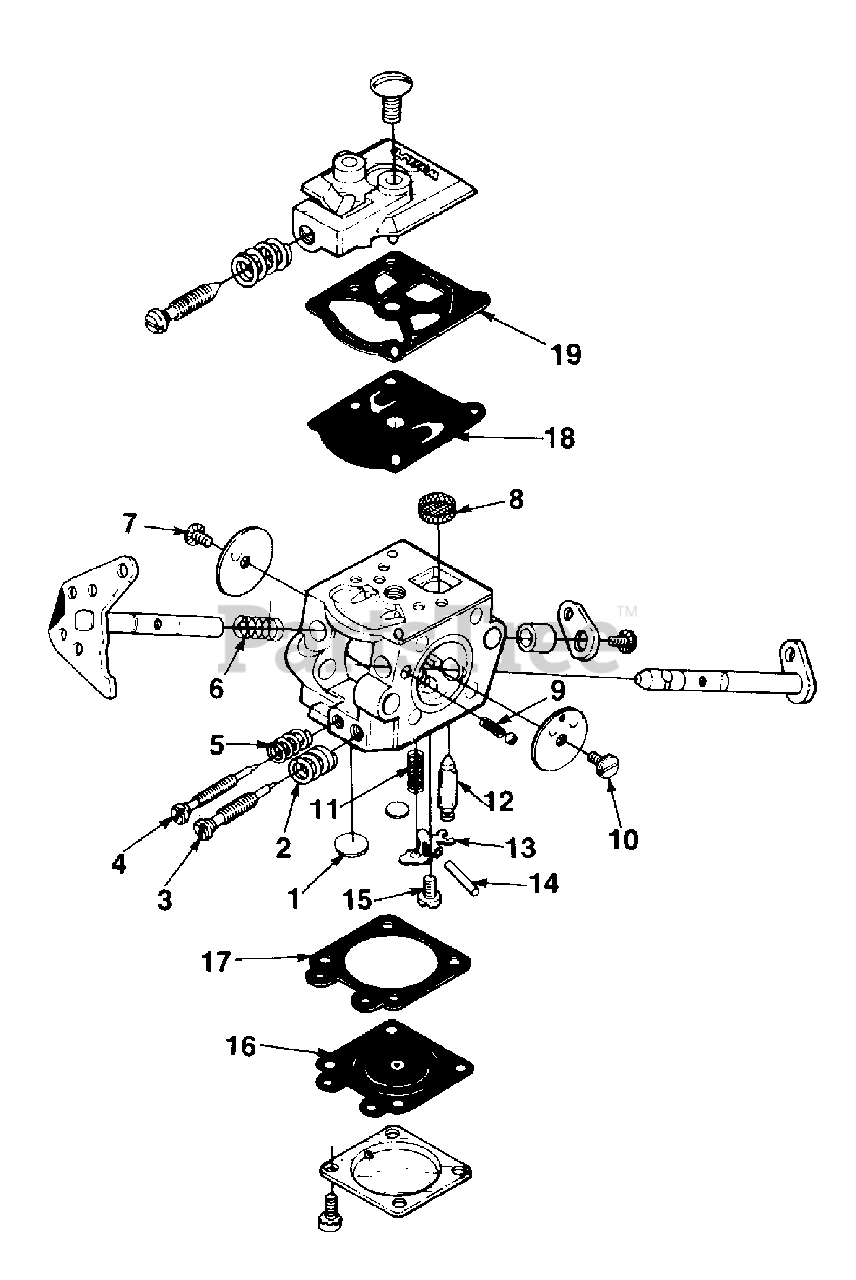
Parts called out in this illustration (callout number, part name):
1	REPAIR KIT
2	REPAIR KIT
3	REPAIR KIT
4	REPAIR KIT
5	REPAIR KIT
6	REPAIR KIT
7	REPAIR KIT
8	REPAIR KIT
9	REPAIR KIT
10	REPAIR KIT
11	REPAIR KIT
12	REPAIR KIT
13	REPAIR KIT
14	REPAIR KIT
15	REPAIR KIT
16	REPAIR KIT
17	REPAIR KIT
18	REPAIR KIT
19	REPAIR KIT
